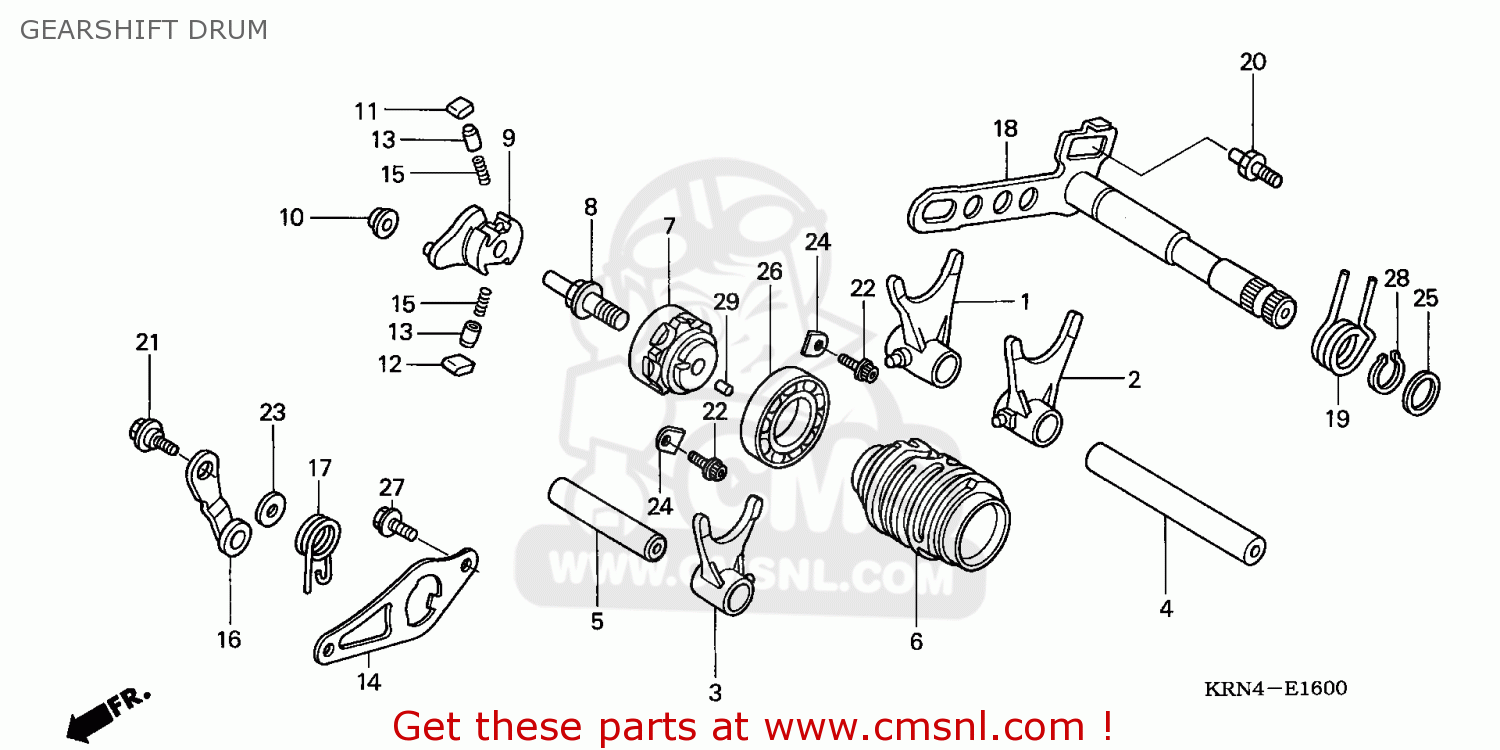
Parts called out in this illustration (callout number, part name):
1	FORK R,GEAR SHIFT
2	FORK L,GEAR SHIFT
3	FORK C,GEAR SHIFT
4	SHAFT A,SHIFT FOR
5	SHAFT B,SHIFT FOR
6	DRUM,GEAR SHIFT
7	CENTER,SHIFT DRUM
8	PIN.SHIFTER
9	SHIFTER,DRUM
10	COLLAR,DRUN SHIFT
11	PAWL A,RATCHET
12	PAWL B,RATCHET
13	PLUNGER,PAWL
14	PLATE,GUIDE
15	SPG PAWL PLUNGER
16	STPR COMP DRUM
17	SPG,DRUM STPR
18	SPDL COMP,GEAR SH
19	SPG,SHIFT RETURN
20	PIN,GEAR SHIFT RE
21	PIVOT,SHIFT DRUM
22	BOLT SOC FLG 6X14
23	WASHER,6.1MM
24	PL,BEARING HOLD
25	WASHER,THRUST 14
26	BRG,BALL RADIAL 6
27	BOLT,HEX.,6X16
28	CIRCLIP,EX,14
29	ROLLER,4X8
